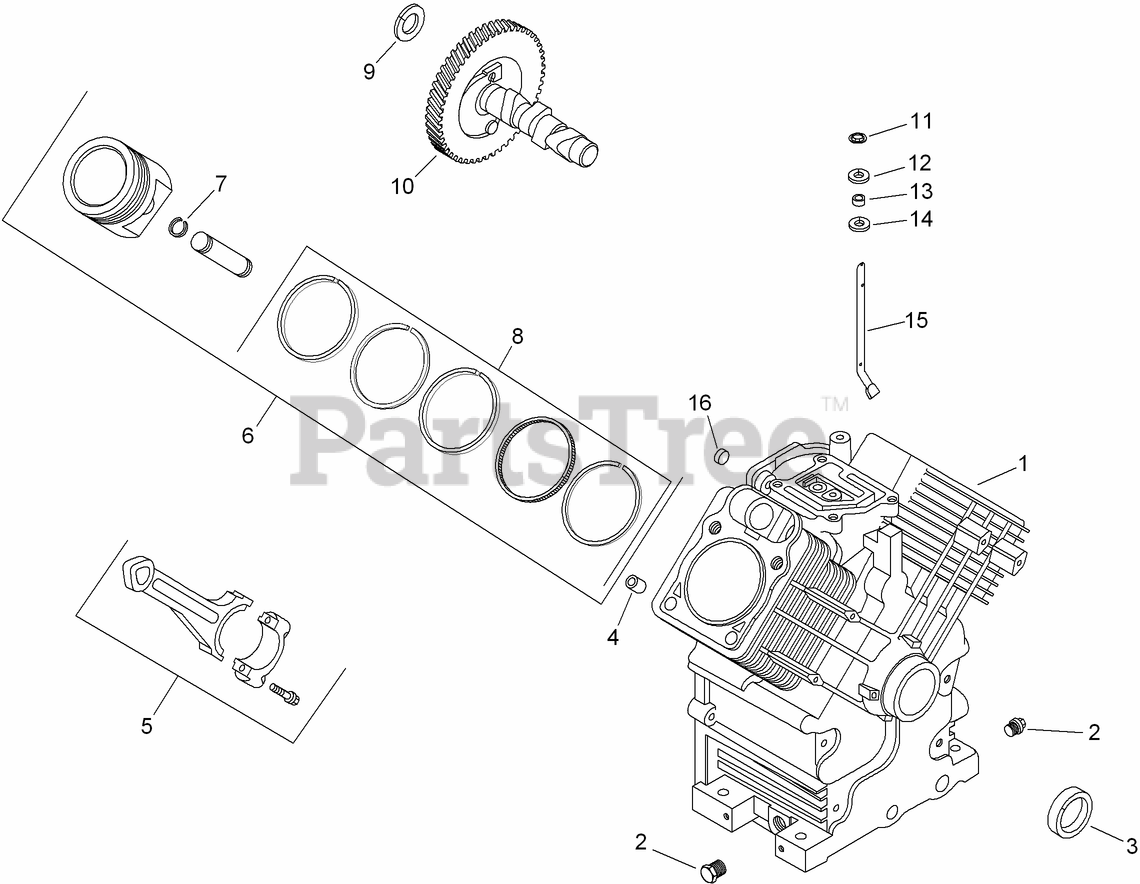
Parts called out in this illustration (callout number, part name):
1	MINI BLOCK (C I BORE)
2	PLUG-PIPE HEAD, 3/8
3	SEAL-OIL (HELIX LIP)
4	PIN-LOCATING
5	ROD-CONNECTING (STD)
5	ROD-CONNECTING (.25)
6	PISTON AND RING KIT (STD) (INCLUDES 7, 8)
6	PISTON W/RING SET (.08)
6	PISTON W/RING SET (.25)
6	PISTON W/RING SET (.50)
7	RETAINER-PIN, PISTON
8	PISTON RING SET (STD)
8	PISTON RING SET (.08)
8	PISTON RING SET (.25)
8	PISTON RING SET (.50)
9	SHIM-CAMSHAFT (WHITE .028)
9	SHIM-CAMSHAFT (BLUE .03)
9	SHIM-CAMSHAFT (RED .032)
9	SHIM-CAMSHAFT (YELLOW .034)
9	SHIM-CAMSHAFT (GREEN .036)
9	SHIM-CAMSHAFT (GRAY .038)
9	SHIM-CAMSHAFT (BLACK .04)
10	CAMSHAFT KIT (INCLUDES 25 357 14-S)
11	RETAINER-RING
12	WASHER-FLAT (9MM)
13	SEAL-CROSS SHAFT, GOVERNOR
14	WASHER-FLAT (11/32)
15	SHAFT-CROSS, GOVERNOR
16	PLUG-CUP
